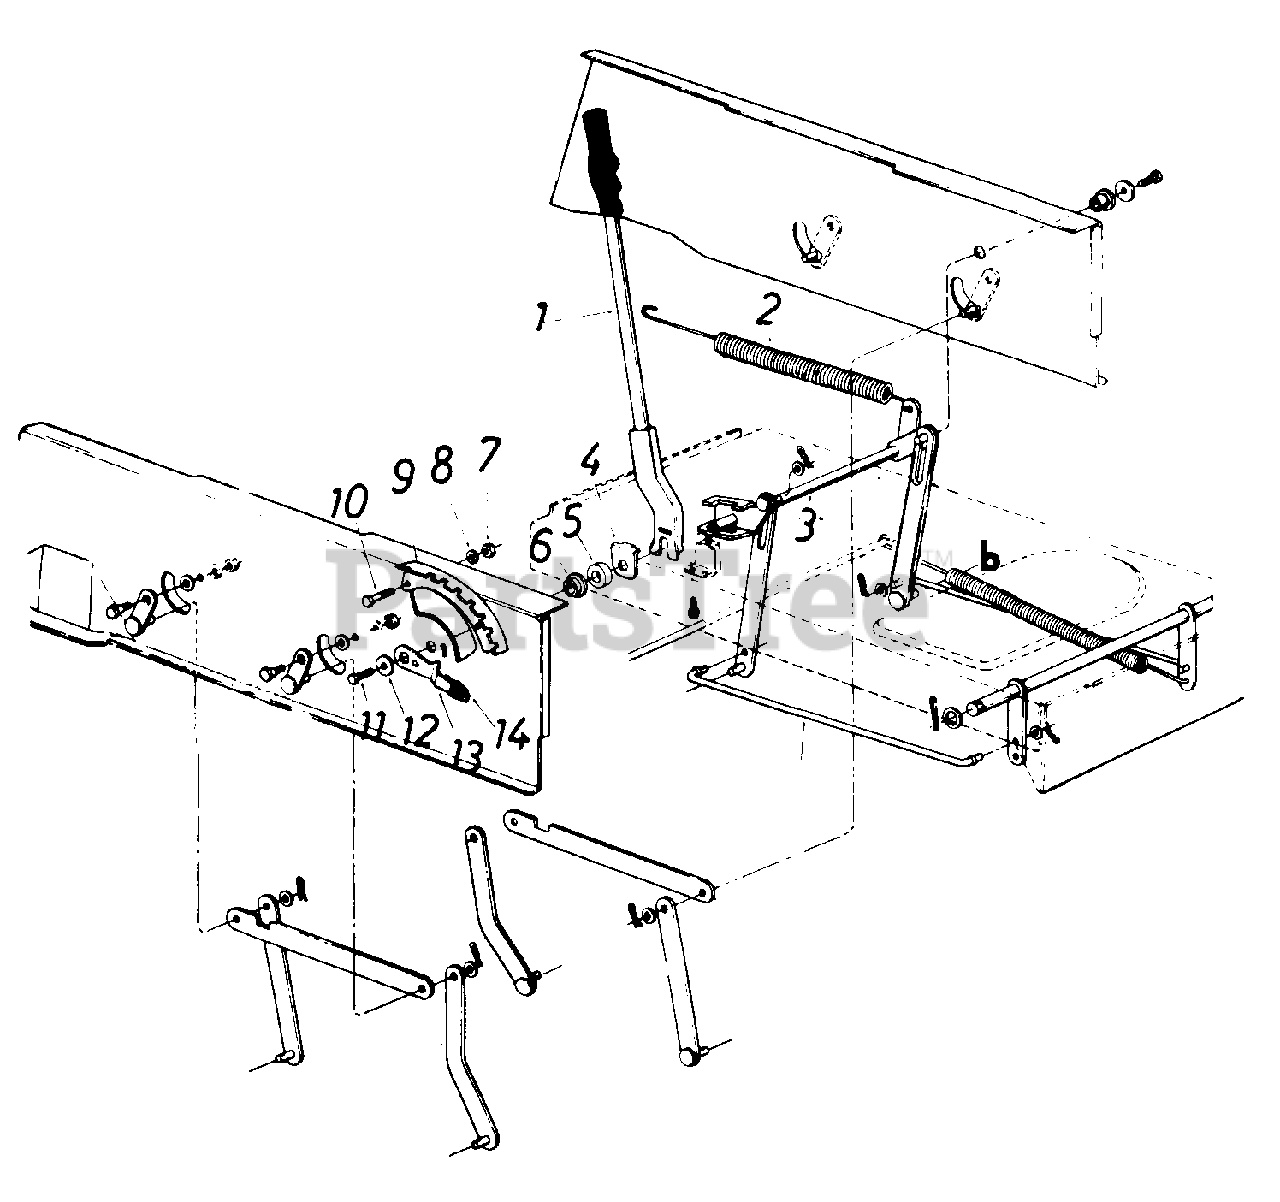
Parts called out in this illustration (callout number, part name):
1	Lift Handle Ass'y.
2	Extension Spring .99" O.D. x 11" Lg.
5	Rubber Wash. 1.50" O.D. x .63" I.D.
6	Flange Wash. .628" I.D. x 1.25" O.D.
7	Hex Nut 5/16-18 Thd.
8	L.-Wash. 5/16" I.D.
9	Index Bracket
10	Hex Bolt 5/16-18 x .75" Lg.
11	Hex Wash. Hd. Self-Tap Scr. 5/16-18x.62" Lg.
12	Fl.-Wash. .344" I.D. x 1.25" Lg.
13	Deck Lift-Down Stop
